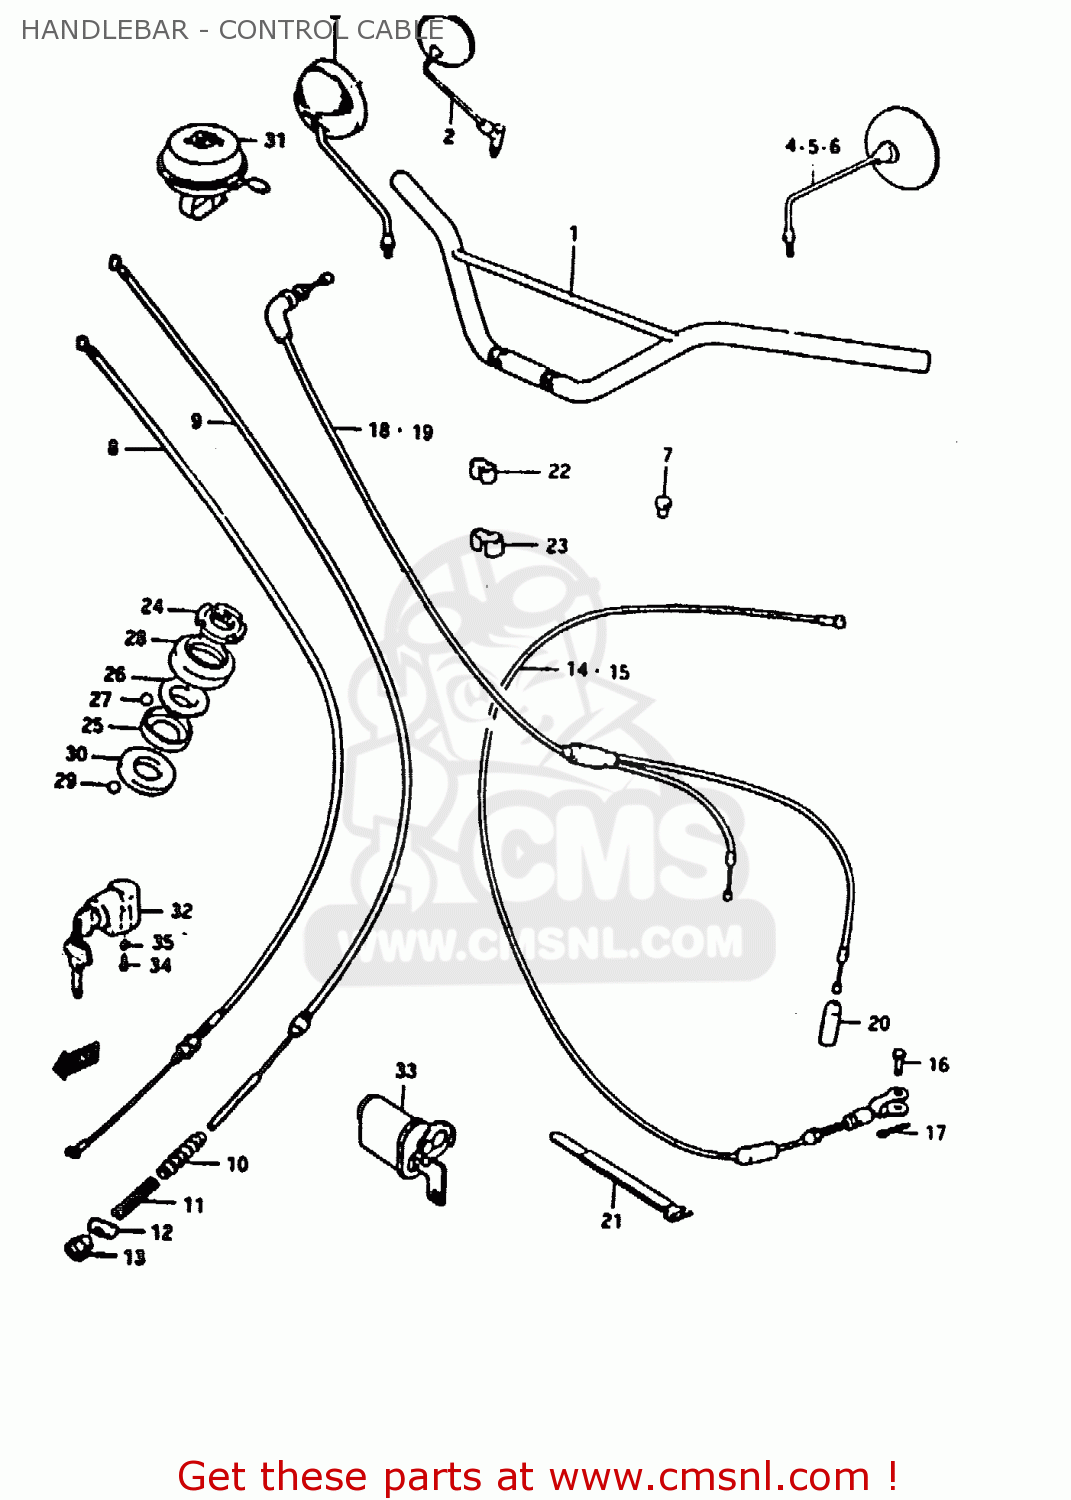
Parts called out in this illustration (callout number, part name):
1	HANDLEBAR
2	MIRROR ASSY, REAR VIEW
7	CAP
8	CABLE ASSY, BRAKE
14	CABLE ASSY,CLUTCH
16	PIN(L:13)
17	PIN
18	CABLE ASSY, THROTTLE
20	SEAL,DUST(7X18X30)
21	CLAMP
24	NUT,STEERING STEM(25X44X10)
25	RACE,STEERING INNER UPR
26	RACE,STEERING OUTER UPR
27	BALL
28	DUST SEAL,STEERING UPR
29	BALL
30	LACE,STEERING INNER LWR
32	LOCK ASSY,STEERING
34	SCREW
35	LOCK WASHER
